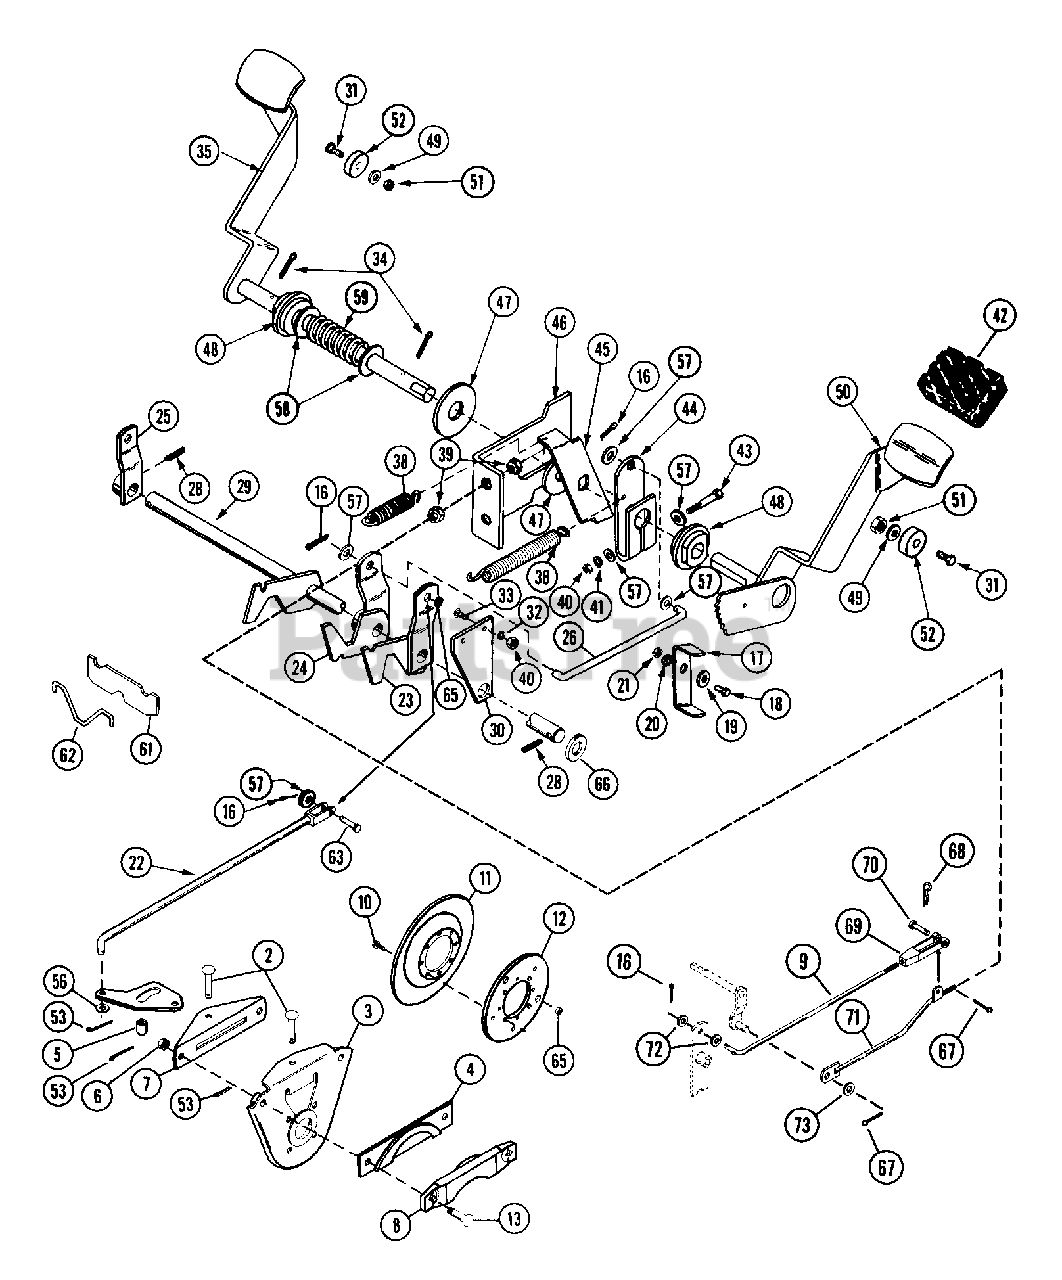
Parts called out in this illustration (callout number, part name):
1	BRAKE ARM
2	PIN-CLEV .371X1.62 YWZC
3	PLATE, CALIPER MOUNTING
4	FRICTION PLATE
6	NUT-LK-NYL .375-16 PL
6	PRESSURE PLATE
8	CALIPER PLATE
9	NEUTRALIZER ROD
9	SHIFT ROD
10	BLT-SERHFWH .25-20X.50 PL
12	CARRIER
13	BLT-RDHDSQNK .38-16X3.50 GR5PL
16	PIN-COTR .09X.75 PL
17	BRAKE LATCH
18	BLT-HEX .25-20X.75 PL GR2
19	WSHR-FL-STL.281X.62X.065 PL
20	SPACER BUSHING .37 X .26 X .14
21	NUT-LK-CTR .250-20 PL
22	BRAKE ROD
23	BRAKE ARM
25	BRAKE ARM
26	BRAKE ROD
28	PIN-GRV .250X1.25 TP A
29	BRAKE SHAFT
31	BLT-HEX .31-18X.88 PL GR2
32	WSHR-LK .375X.115 HVY PL
33	BLT-RDHDSQSHNK .38-16X1.00 PL
34	PIN-COTR .18X1.25 PL
35	L. H. LEVER
37	GROMMET 1.0ID X 1.38 OD
38	SG-TENS .090X.75X3.50 WLD 34
39	NUT-LK-CTR .50-13
40	NUT-HEX .375-16
41	WSHR-LK .375X.094 MED PL
42	PEDAL PAD
43	BLT-HEX .38-16X2.25 GR2
44	ARM-BRAKE
45	NEUTRALIZER ARM
46	NEUTRALIZER PLATE
47	WSHR-FL-STL .755X2.000X.125
48	BSHG-FLG .750X1.750X.875X2.125
49	WSHR-FL-STL .38X.875X.083 PL
50	R. H. LEVER
51	NUT-LK .312-18 GR A PL
52	SPACER .344X1.000X.375
53	PIN-COTR .09X.75 PL
56	WSHR-FL-STL .323X.625X.062 PL
57	WSHR-FL-STL.406X.812X.065PL
58	WSHR-FL-STL .755X1.375X.062 PL
59	SG-COMP .148X1.23X2.53 WLD87
61	BALANCE LINK
63	PIN-CLEV .373X1.12 YWZC
65	GROMMET
66	WSHR-FL-STL .754X1.125X.062 PL
67	PIN-COTR .12X1.0 PL
68	PIN-HAIR INT .08X.18X1.18
69	YOKE
70	CLEVIS PIN
71	SHIFT ROD
72	WSHR-FL-STL .323X.625X.062 PL
73	WSHR-FL-STL .531X1.062X.095 PL
